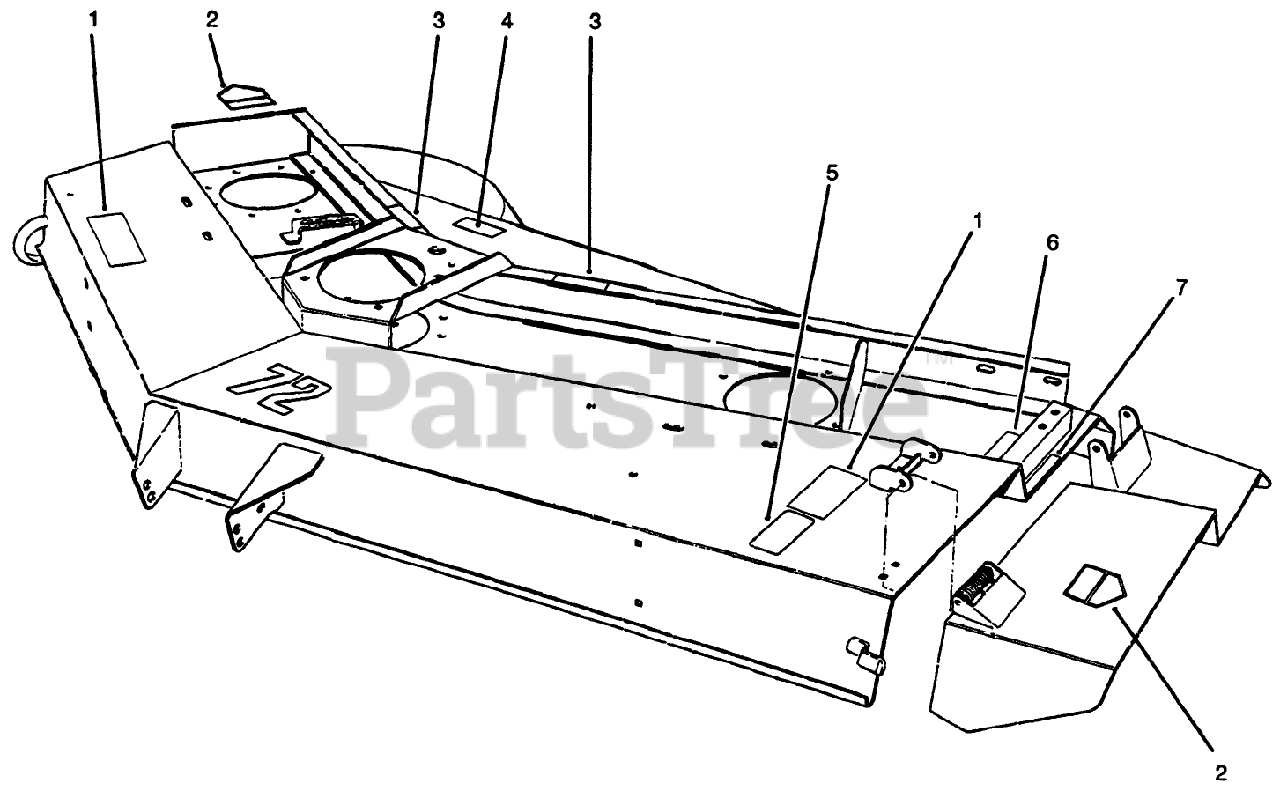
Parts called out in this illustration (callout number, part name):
1	DECAL-DANGER
2	DECAL-DANGER, INT'L
3	DECAL-DANGER
4	DECAL BLANK
5	DECAL-WARNING
6	DECAL-TORQUE, BLADE BOLT
7	DECAL-WARNING, DEFLECTOR
